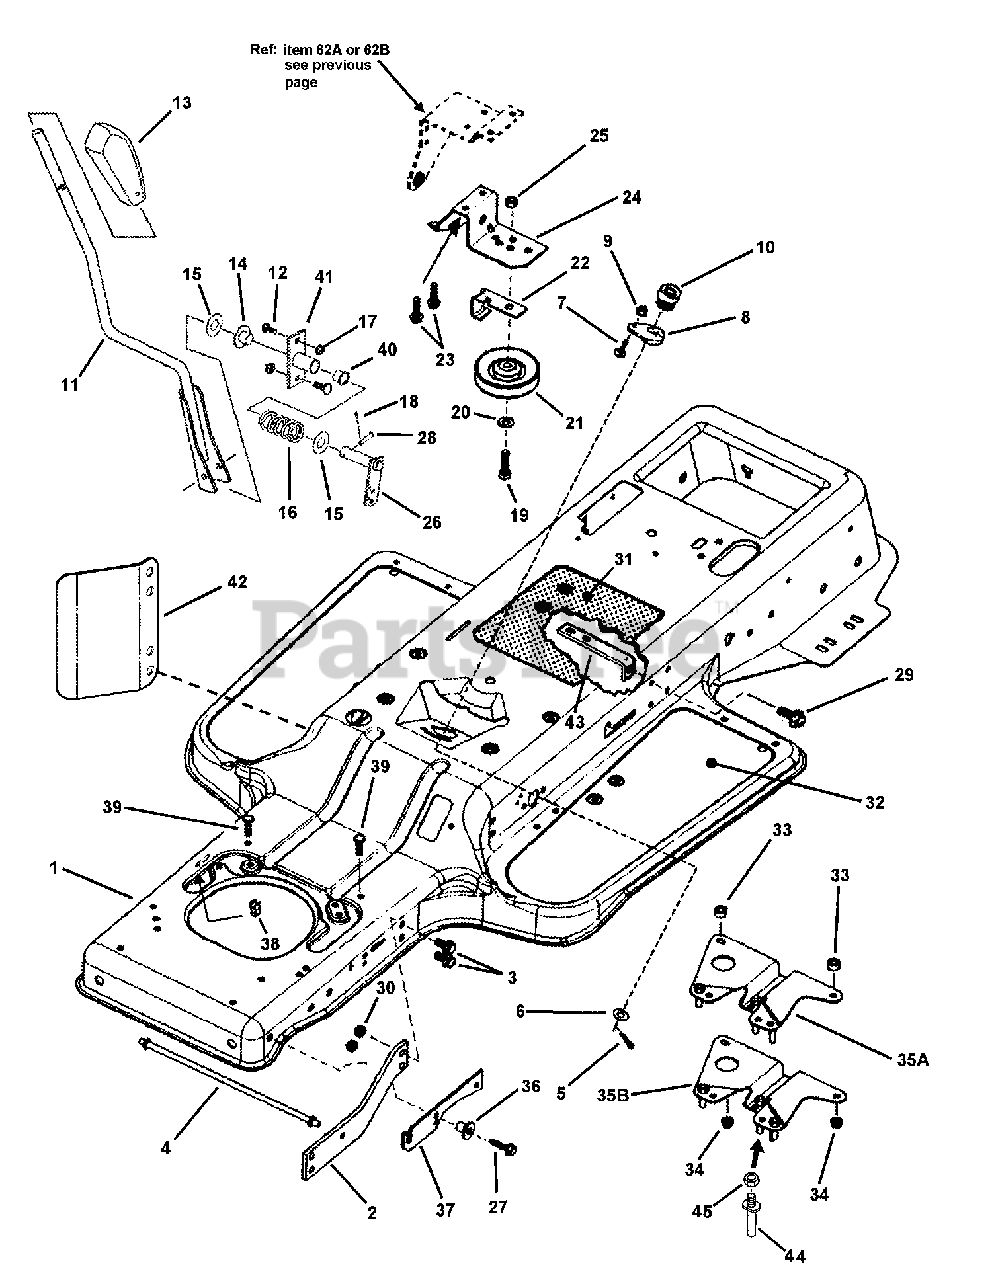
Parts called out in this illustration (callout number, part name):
1	FRAME, Tractor (I piece)
2	BRACE, Frame
3	BOLT, 3/8-16 x 3/4" Hex Flange Lock
4	BELT GUIDE
5	PIN, 1/8 x 3/4" Cotter
6	SHIM WASHER, .50 x .75 x .03
7	BOLT, 1/4-20 x 5/8" Short Neck Carriage, GR 5
8	ASSEMBLY, Steering Adjuster
9	NUT, 1/4-20 Hex Flange Lock
10	GEAR, Pinion, Steering
11	WELDMENT, Shift Handle- TTK46
12	BOLT, 5/16-18 x 3/4" Short Neck Carriage, GR 5
13	LEVER Shift Handle
14	BUSHING, 3/4 - 1.62 Flange
15	THRUST WASHER
16	SPRING, Shift Detent
17	NUT, 5/16-18 Hex Flange Lock, GR 5
18	PIN, 3/32 x 3/4" Cotter
19	SCREW, 3/8-16 x 1-1/2" Hex Head Cap, GR 5
20	WASHER, 3/8" Flat
21	PULLEY, Idler V, 3.30 HA
22	BELT GUIDE, 3-1/2" Dia.
23	SCREW, 5/16-18 x 1-1/4" Swage
24	SUPPORT, PTO Lever
25	NUT, 3/8-16 Hex Center Lock, GR 5 or B
26	WELDMENT, Arm
27	SCREW, 5/16-18 x 1-1/2" Hex Washer Self-Tap
28	PIN, 1/4 x 1-5/8" Clevis
29	SCREW, 5/16-18 x 5/8" Hex Washer Self-Tap
30	NUT, 3/8-16 Hex Flange Lock
31	DECAL, Instructions Frame Top Electric Clutch
32	FOOT PAD, Textured (Black)
33	SPACER, .340 I.D. x .63 O.D. x .310 thick
34	NUT, 5/16-18 Hex Flange Lock, GR 5
35A	WELDMENT, Anti-Spin/Belt Guide-42
35B	WELDMENT, Anti-Spin/Belt Guide
36	BUSHING, Flange
37	BRACKET, Hood Pivot
38	WIRE CLIP, .28 x .41
39	SCREW, 5/16-18 x 1" Hex Head Cap, GR 2
40	BUSHING, 3/4 - I" Flange (nylon)
41	WELDMENT, Pivot Plate
42	HEAT SHIELD, (Foot Rest)
43	ANCHOR, Blade Brake
44	PIN, .31 O.D. x 3/4"
45	NUT, 5/16-18 Hex Center Lock, GR 5 or B
